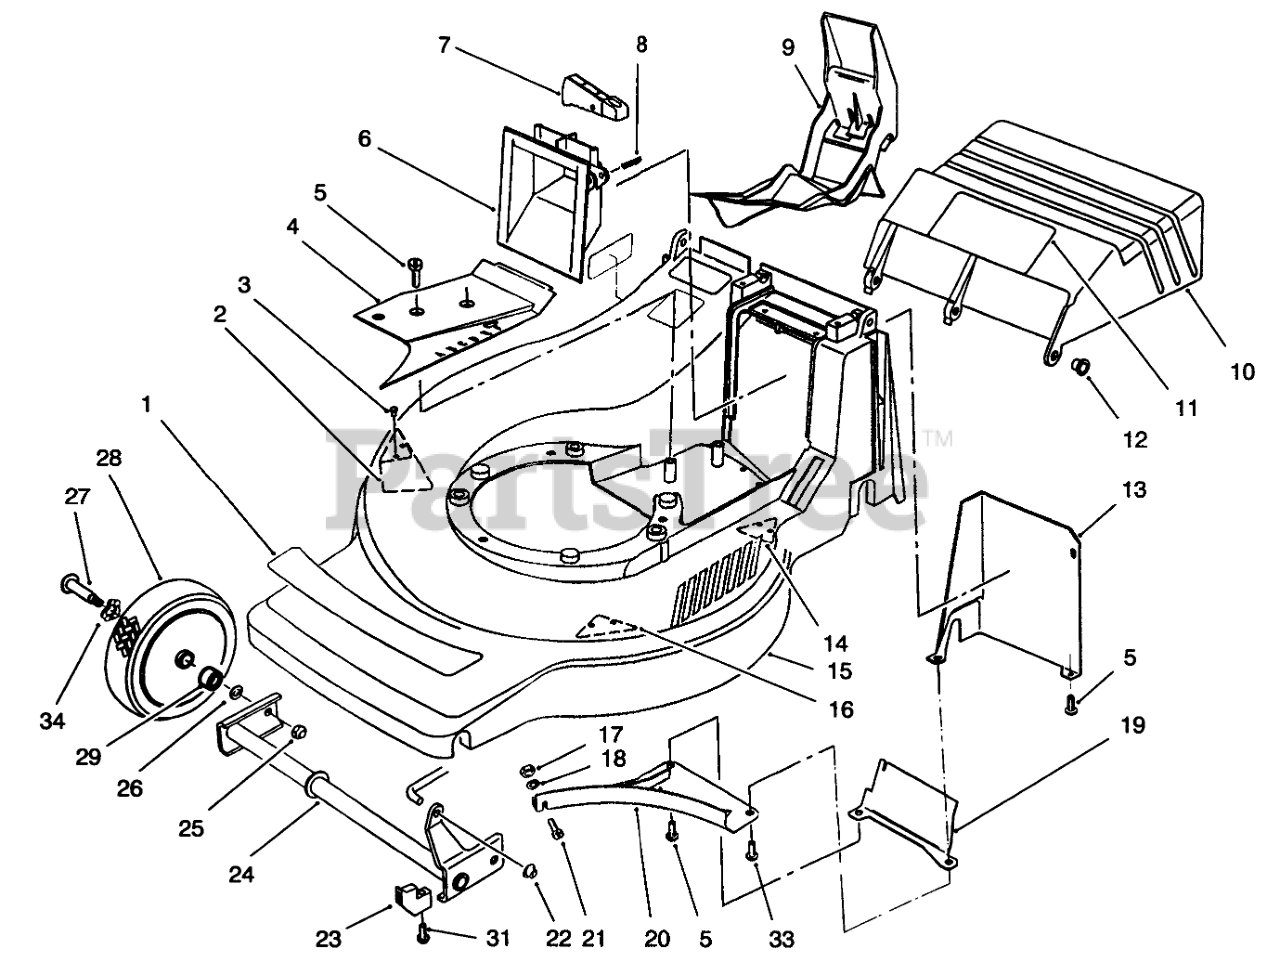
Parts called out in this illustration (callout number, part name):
1	DECAL - DECK
2	KICKER
3	SCREW-PPH
4	COVER - BELT
5	SCREW-RH
6	GRIP - LOWER
7	TRIGGER - HOC
8	PIN-SPIRAL
10	Door-Discharge
11	DECAL - DANGER
12	BUSHING-DOOR
13	COVER - SHIELD
14	KICKER
15	Housing Assembly (Incl. Ref. # 2,3,14,16)
16	KICKER
17	NUT-LOCK, NI
18	WASHER-FLAT
19	BAFFLE-BAGGER, REAR
20	BAFFLE
21	SCREW-PPH
22	NUT-PUSH
23	RETAINER - AXLE
24	AXLE-FRONT
25	NUT-LOCK
26	WASHER
27	WHEEL BOLT
28	WHEEL-FRONT
29	BUSHING
31	SCREW-RETAINER
33	SCREW-BAFFLE
34	WASHER-WAVE
